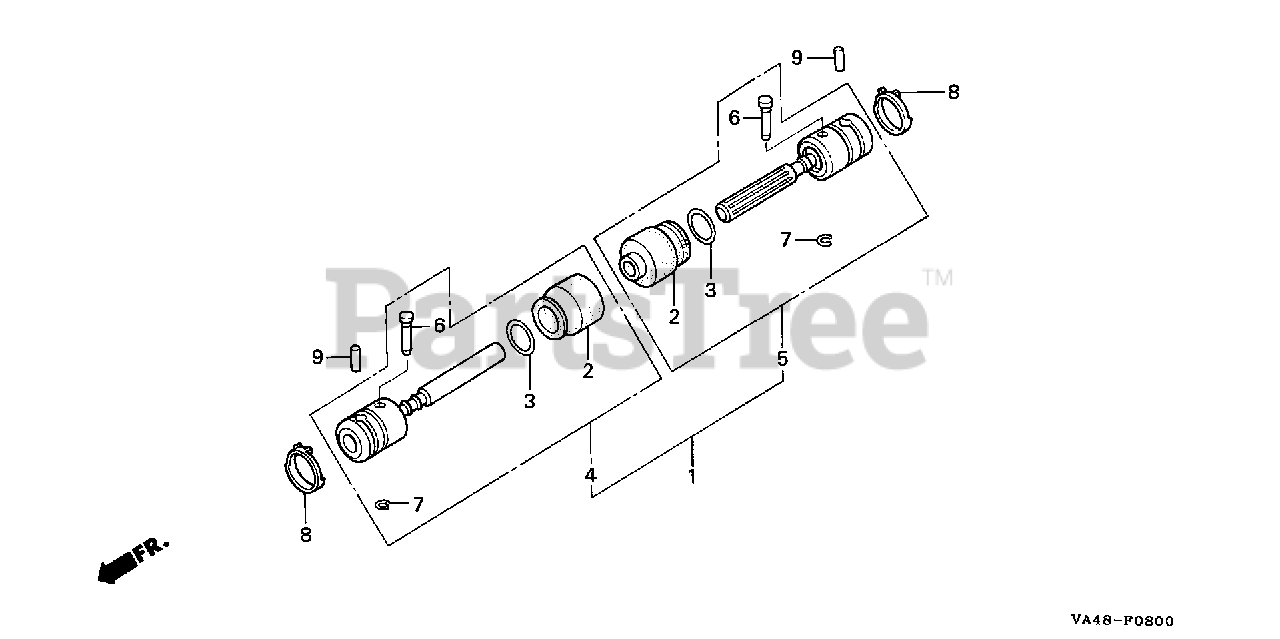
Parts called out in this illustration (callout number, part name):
1	JOINT ASSY.
2	BOOT, JOINT
3	RING, SEAL
4	JOINT SUB-ASSY.
4	JOINT SUB-ASSY. (A)
5	JOINT SUB-ASSY. (B)
8	CLIP, CLUTCH SHAFT
9	ROLLER (4X17.8)
